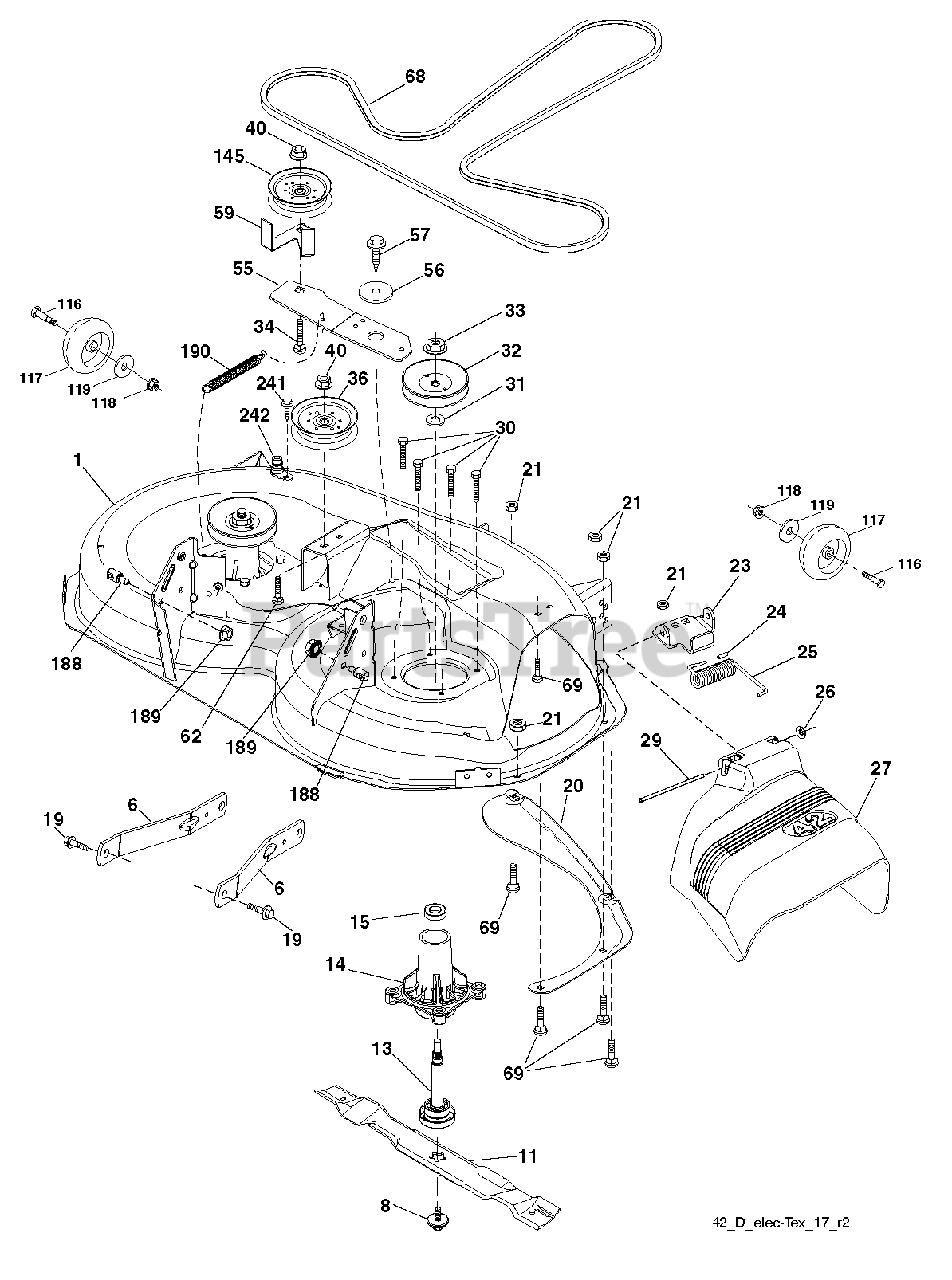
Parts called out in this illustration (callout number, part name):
1	DECK.WELDMENT.42"
6	ARM.SUSPENSION.MOWER.R
8	BOLT.WASHER.ASM.7/16-2
11	42" HI-LIFT BLADE
13	SHAFT.ASM.MDRL.N/GREASE.38
14	HOUSING MANDREL
19	BOLT.SHOULDER
20	BAFFLE.VORTEX
21	LOCKNUT
23	BRKT.DEFLECTOR.38"2005+
24	CAP-SLEEVE LT
25	SPRING.TORSION.DEFLECT
26	NUT PUSH M
27	SHIELD.DEFLECTOR.MOWER.42"BLAC
29	ROD.HINGE
30	SCREW, WASHER HEAD
31	WASHER.SPACER.MANDREL
32	PULLEY/MANDREL
33	NUT.FLANGE.LOCK.TOP
34	BOLT.3/8-16X1.50
36	PULLEY.IDLER.2006
40	NUT LOCK FLG 3/8-16 UNC
55	IDLER.ARM.42"
56	SPACER.RETAINER
57	SCREW 3/8-16X1
59	GUARD, BELT
62	BOLT
68	BELT V SECONDARY
69	BOLT
117	WHEEL.GAGE.HALF.SPOKED
118	NUT LOCK FLG 3/8-16 UNC
119	WASHER
145	PULLEY.IDLER.48"PRIMARY
188	STUD.FASTNER.W/ANTI-ROTATE
189	NUT LOCK HEX FLANGE 5/16-18
190	SPRING.MOWER.DRIVE.ELECTRIC
242	PORT.WASHOUT
